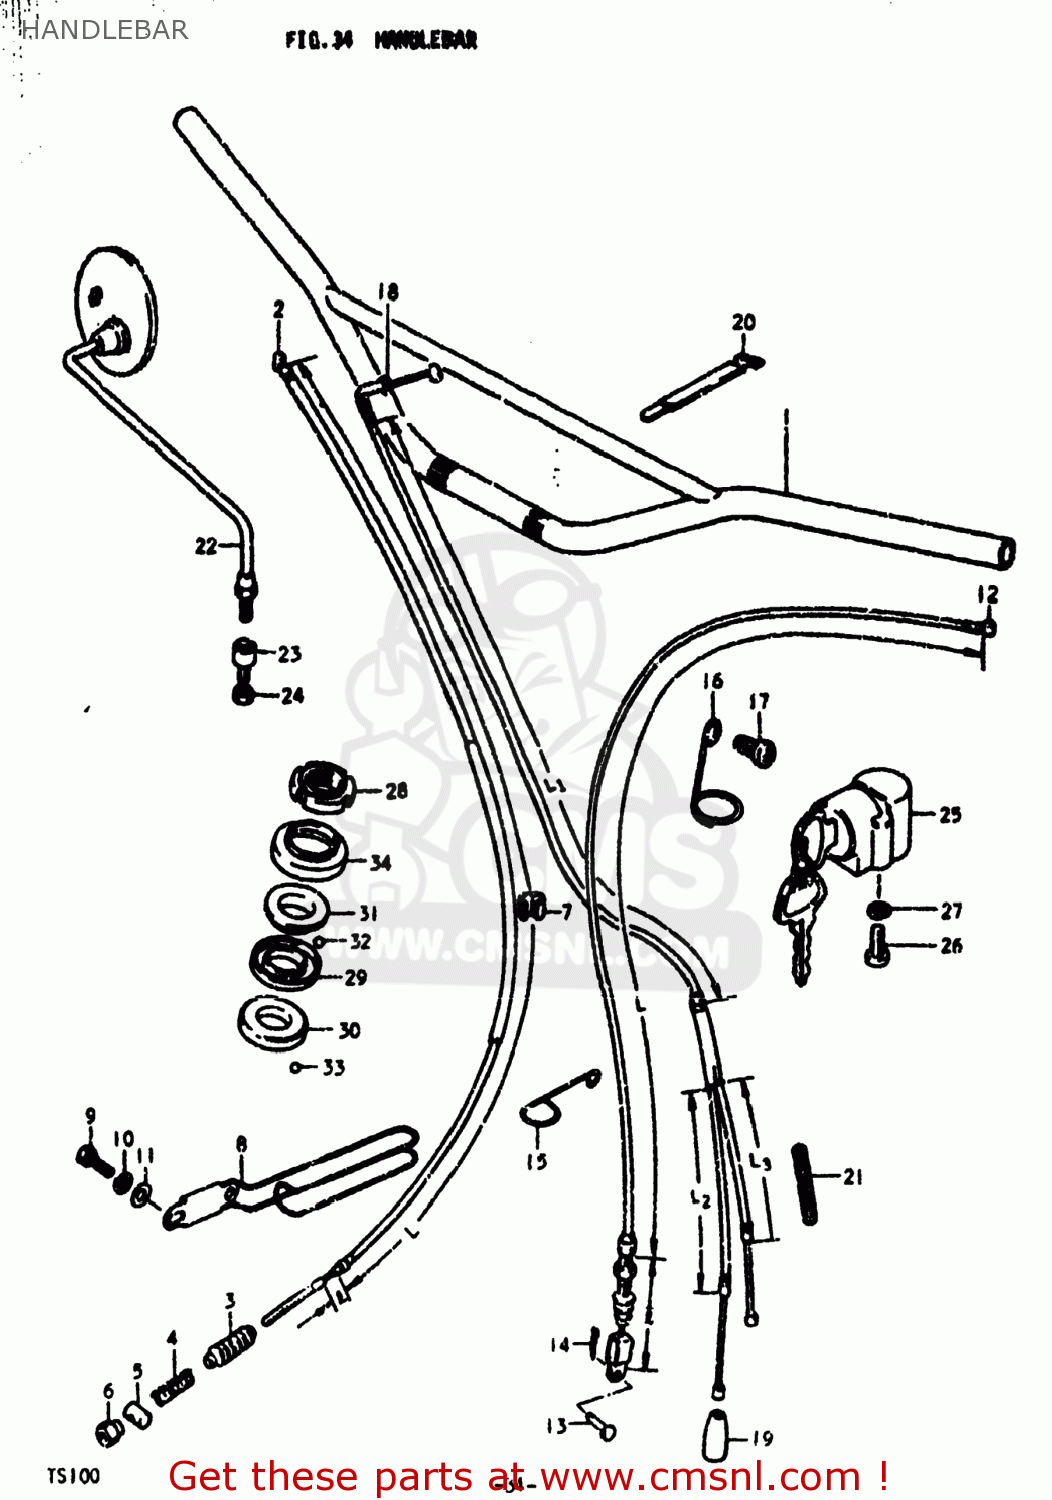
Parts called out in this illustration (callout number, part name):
1	HANDLEBAR
2	CABLE ASSEMBLY,FRONT BRAKE
3	SEAL,DUST(7X16X75)
4	SPRING
5	PIN,10X19
6	NUT
7	CLIP
8	GUIDE,CABLE
9	BOLT 8X12
10	LOCK WASHER
11	WASHER
12	CABLE ASSEMBLY,CLUTCH
13	PIN(L:15)
14	COTTER PIN
15	CLAMP,METER CABLE
16	CLIP,TACHOMETER CABLE
17	SCREW
18	CABLE ASSY,THROTTLE
19	SEAL,DUST(7X18X30)
20	CLAMP
21	PROTECTOR,CABLE
22	MIRROR ASSEMBLY,LEFT
23	CUSHION,REAR VIEW MIRROR
24	NUT
25	LOCK ASSEMBLY,STEERING
26	SCREW
27	LOCK WASHER
28	NUT,STEERING STEM(25X44X10)
29	RACE,STEERING INNER UPR
30	LACE,STEERING INNER LWR
31	RACE,STEERING OUTER UPR
32	BALL
33	BALL
